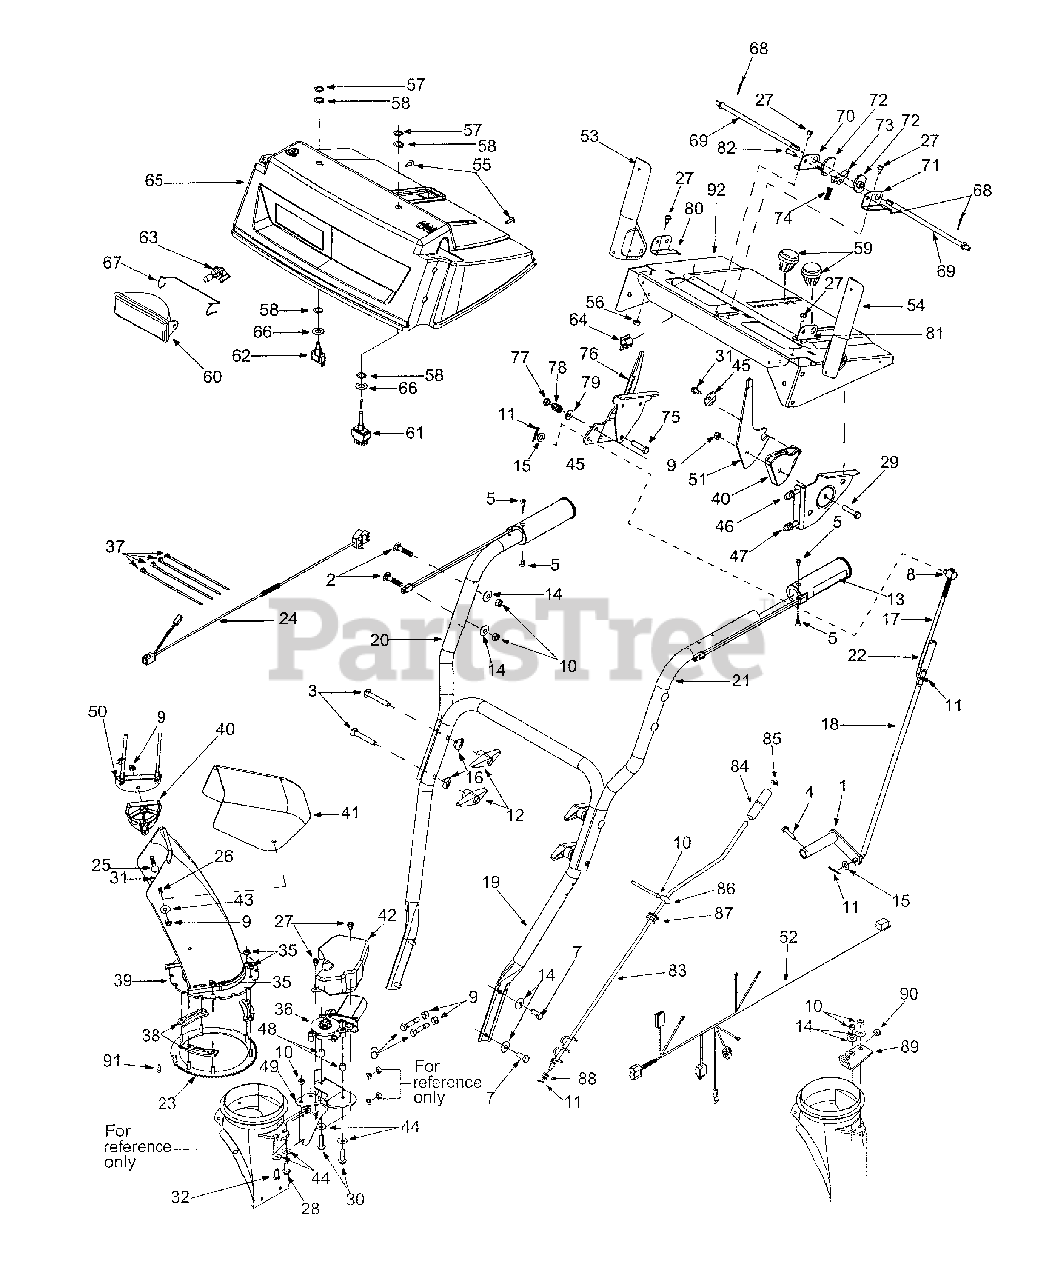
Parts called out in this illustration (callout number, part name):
2	Carriage Bolt 5/16-18 x 1.5"
3	Carriage Bolt 5/16-18 x 2.25"
4	TT Screw 1/4-20 x 1"
5	C-Sunk Screw #10-16x .625"
6	Shear Bolt 5/16-18 x 1.5"
7	Hex Screw 5/16-18 x .75"
8	Ferrule
9	Hex Lock Nut 5/16-18
10	Hex Nut 5/16-18
11	Cotter Pin
12	Handle Knob
13	Grip
14	Belleville Washer
15	Flat Washer
16	Saddle Washer
17	Shift Rod: Upper
18	Shift Rod: Lower
23	Gear Assembly: Ring
24	Electric Harness: Lower
25	Carriage Bolt: 5/16-18 x 1.5"
26	Carriage Bolt: 5.16-18 x .750"
27	TT Screw: 1 /4-20 x 0.5"
28	TT Screw: 5/16-18 x 1"
29	Hex Screw: 5/16-18 x 1.5"
30	TT Screw: 5/16-18 x 1.25"
31	Hex Screw AB: 1 /4-14 x 0.625"
32	Hex Screw: 5/16-18 x .75"
35	Hex Flange Lock Nut
36	Electric Motor: Chute Crank
37	Cable Tie
38	Chute Flange Keeper
39	Lower Chute
40	Cable Guide: Chute Tilt
41	Upper Chute
42	Motor Cover: Chute Rotation
43	5/16 Washer
44	Belleville Washer
45	Special Washer
46	Control Cable
47	Control Cable
48	Spacer
52	Harness Assembly: Upper
53	Handle Assembly RH
54	Handle Assembly LH
55	Special Hex Screw
56	Hex Sems Nut: 1/4-20
58	Lock Ring: Toggle Switch
59	Shift Knob
60	Lamp Housing
61	Toggle Switch: Double Thr.
62	Toggle Switch: Single Thr.
63	Halogen Lamp: 50W, 12V
64	Mounting Clamp
65	Handle Pane
66	Flat Washer
67	Headlight Retainer
68	Cotter Pin: 3/32 x .75
72	Cam Handle Lock
73	Handle Lock Pawl
74	Compression Spring: .36 x 1.0
75	Hex Cap Screw: 3/8-24 x 1.5
78	Comp. Spring: .39 x.6 x .88
79	Bell Washer
82	Clevis Pin
83	Chute Crank Assembly
84	Knob
85	Push Cap
86	Eyebolt
87	Rubber Grommet
88	Flat Washer
90	Plastic Bushing
91	Hex Head Cap Screw 1/4-20
